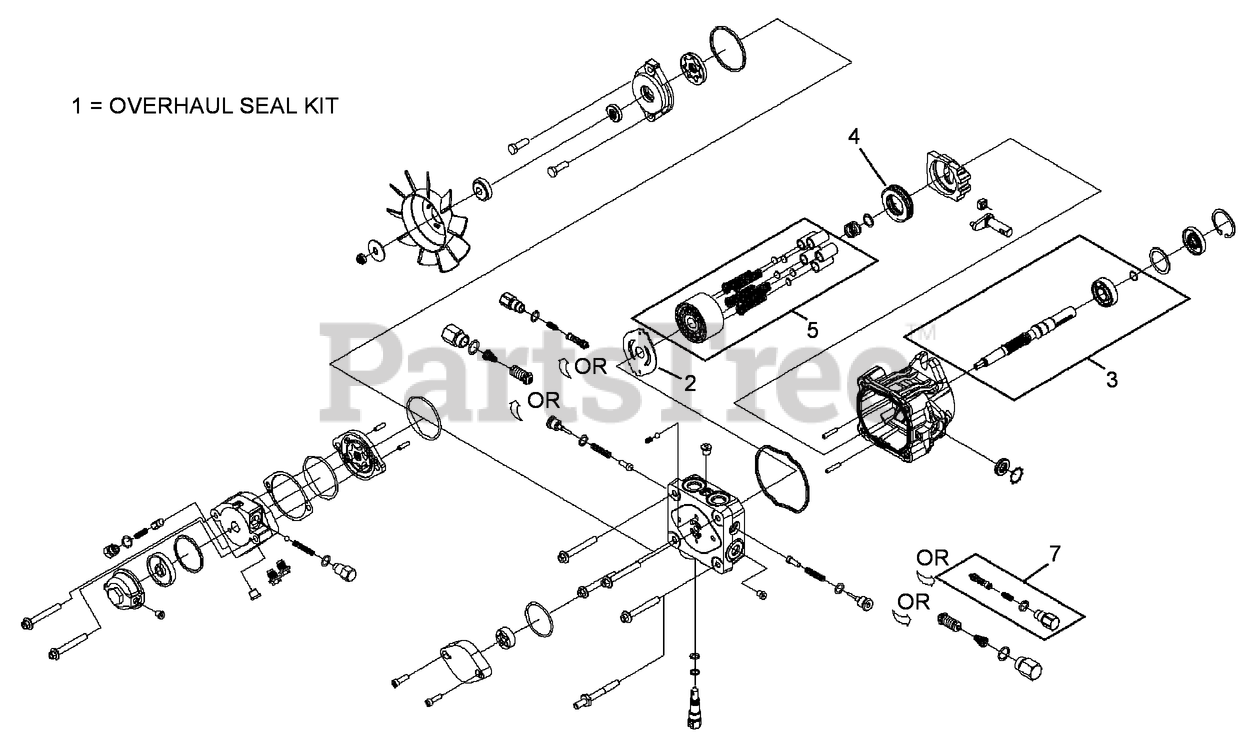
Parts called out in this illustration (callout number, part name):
1	SEAL OVERHAUL KIT
2	Plate-Valve
3	INPUT SHAFT KIT
4	BEARING-THRUST
5	CYLINDER BLOCK KIT
7	SHOCK VALVE KIT
